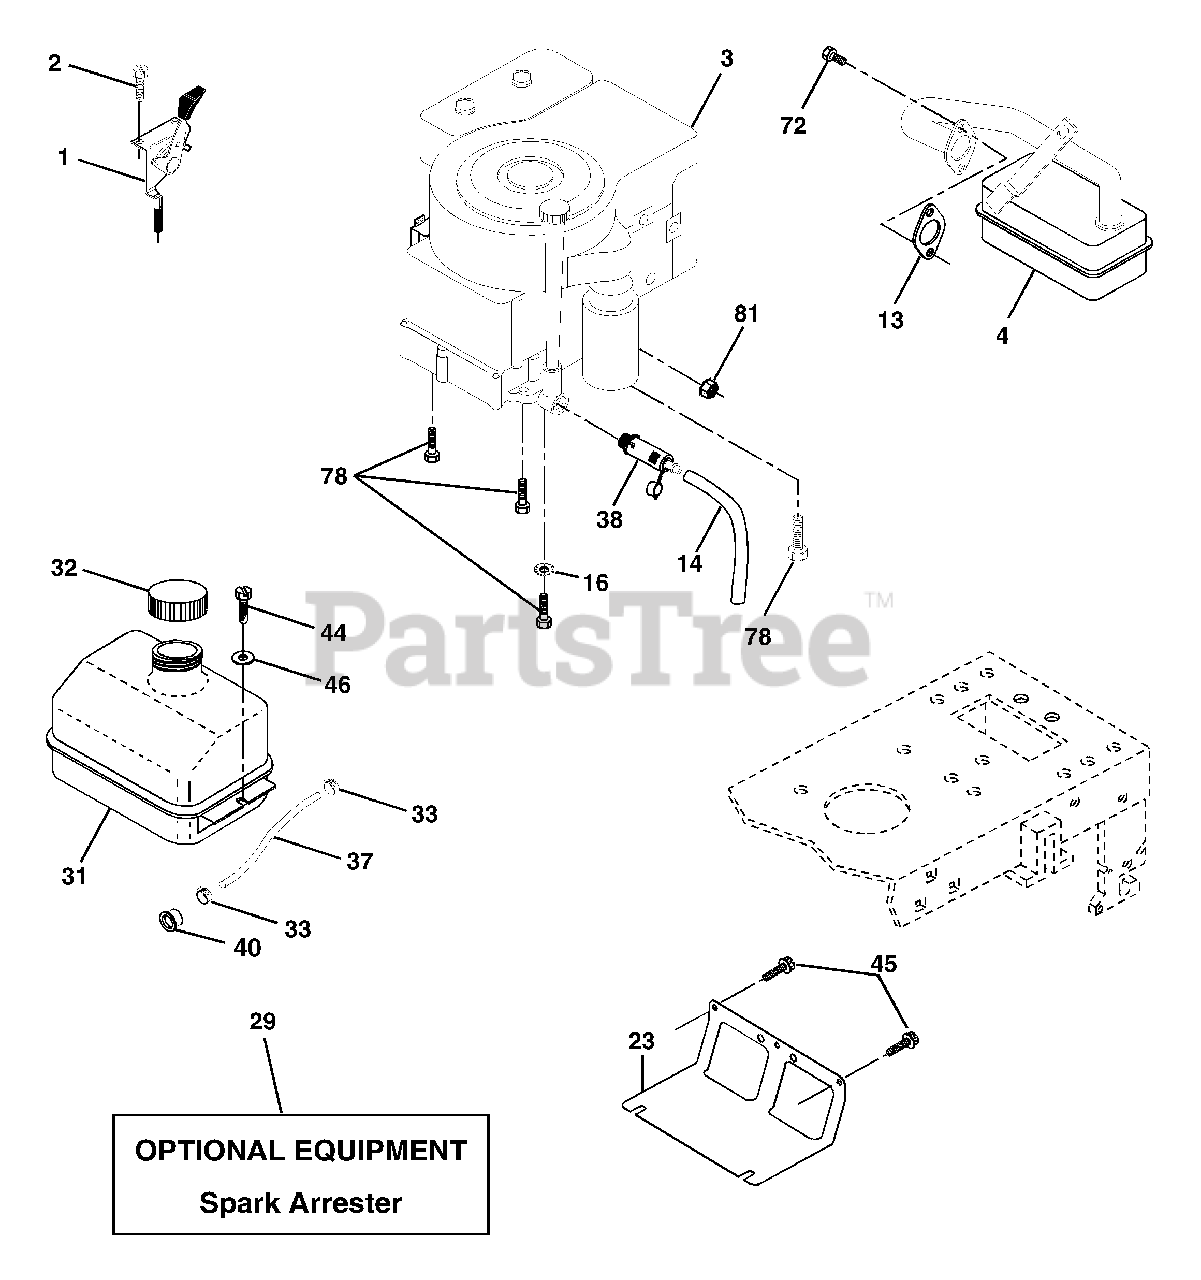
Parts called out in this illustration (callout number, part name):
1	Control Throt /Ch Flag
2	Screw Hex Thd Cut 1/4-20x1/2
4	Muffler Exhaust B&S Lt
13	Gasket 1 313 Id Tin Plated
14	Tube Drain Oil Easy
16	Washer Lock Ext Tooth 3/8
23	Shield Browning/Debris Guard
29	Arrestor Spark
31	Tank Fuel 1 25 Fr
32	Cap Asm Fuel W/sym Vented
33	Clamp Hose Blk
37	Line Fuel 20"
38	Plug Drain Oil Easy
40	Bushing Snap Nyl Blk Fuel Line
44	Screw Hexwsh Thdrol 1/4-20x3/4
45	Screw Hex Wsh Thdrol 3/8-16
46	Washer 9/32 X 7/8 X 16ga
72	Screw Socket Head 5/16-18 x 1
78	Screw 3/8-16x1-1/4
81	Nut Keps Hex 1/4-20 Unc
